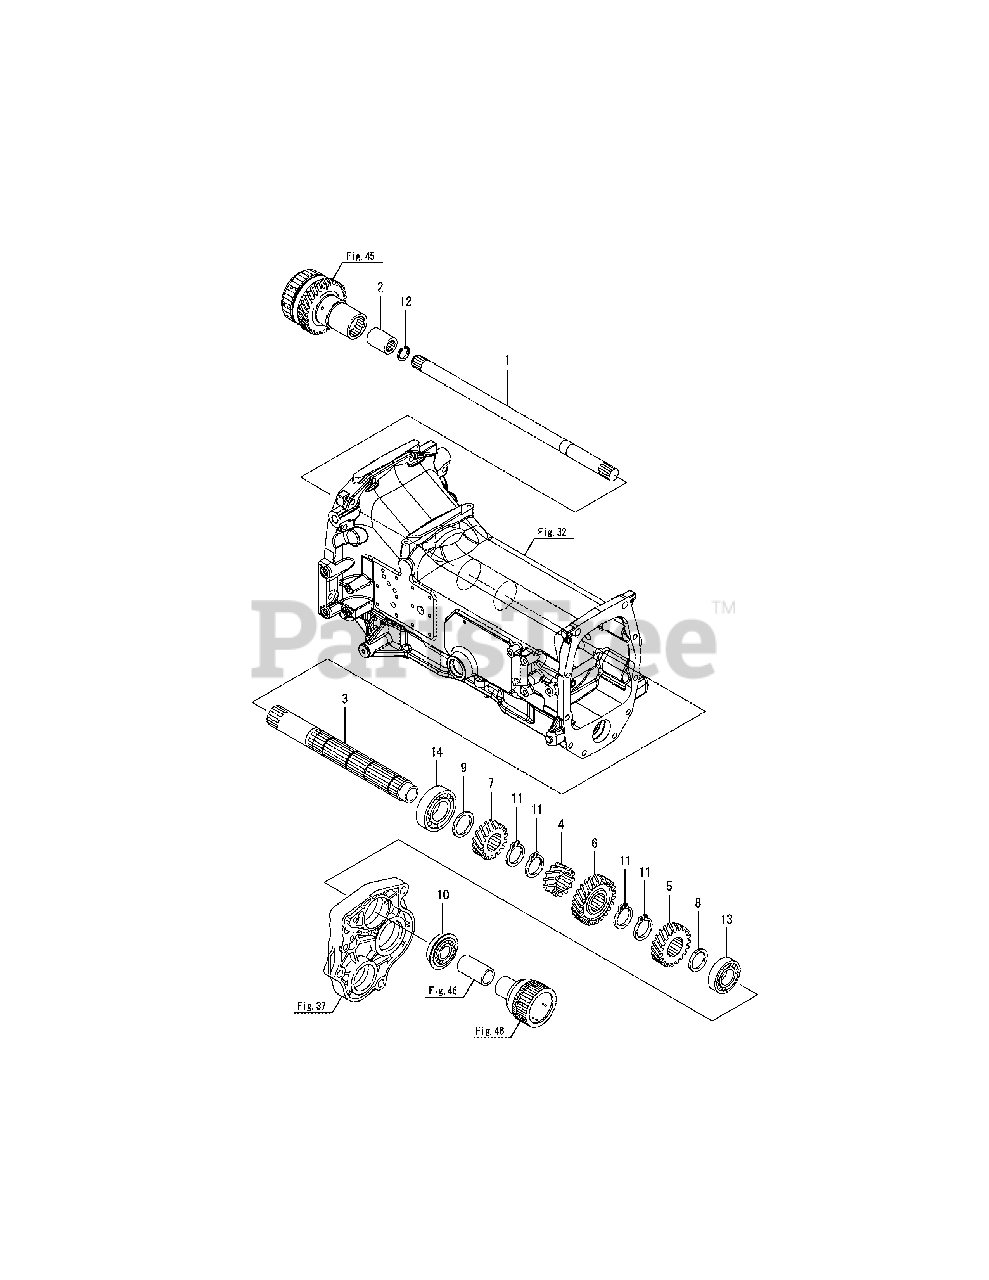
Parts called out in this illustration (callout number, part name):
1	SHAFT, PTO DRIVE
2	COUPLING 13 16/32
8	SPACER 30X40X2
9	SPACER 35X45X2
10	BEARING 63/22NR
